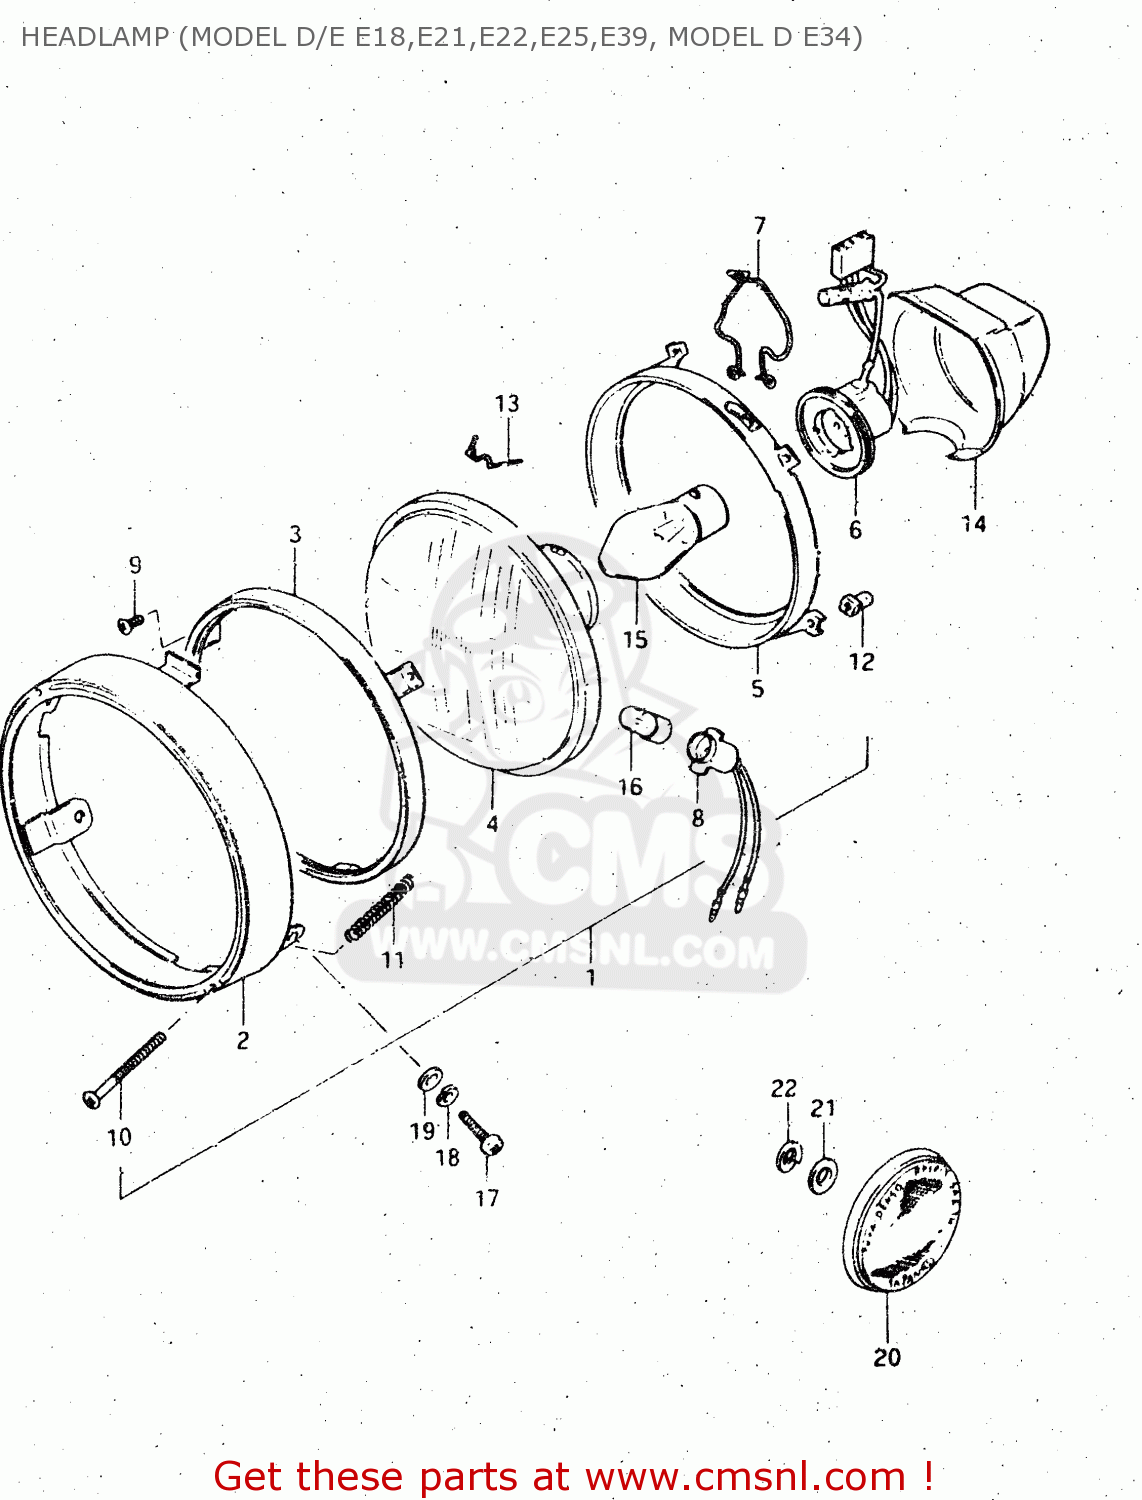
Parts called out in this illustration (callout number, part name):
1	HEADLAMP ASSY
2	RIM
3	RETAINER,HEADLAMP
4	UNIT
5	RING, MOUNTING
6	SOCKET
7	CLAMP,HEADLAMP
8	SOCKET
9	SCREW
10	SCREW,HEADLAMP ADJUST
11	SPRING,ADJUSTING
12	NUT,HEADLAMP ADJUSTER
13	SPRING,HEADLAMP UNIT
14	COVER, SOCKET
15	BULB (6V,35/35W)
16	BULB (6V,4W)
17	SCREW
18	LOCK WASHER
19	WASHER
20	REFLEX REFLECTOR,FR
21	LOCK WASHER
22	WASHER
